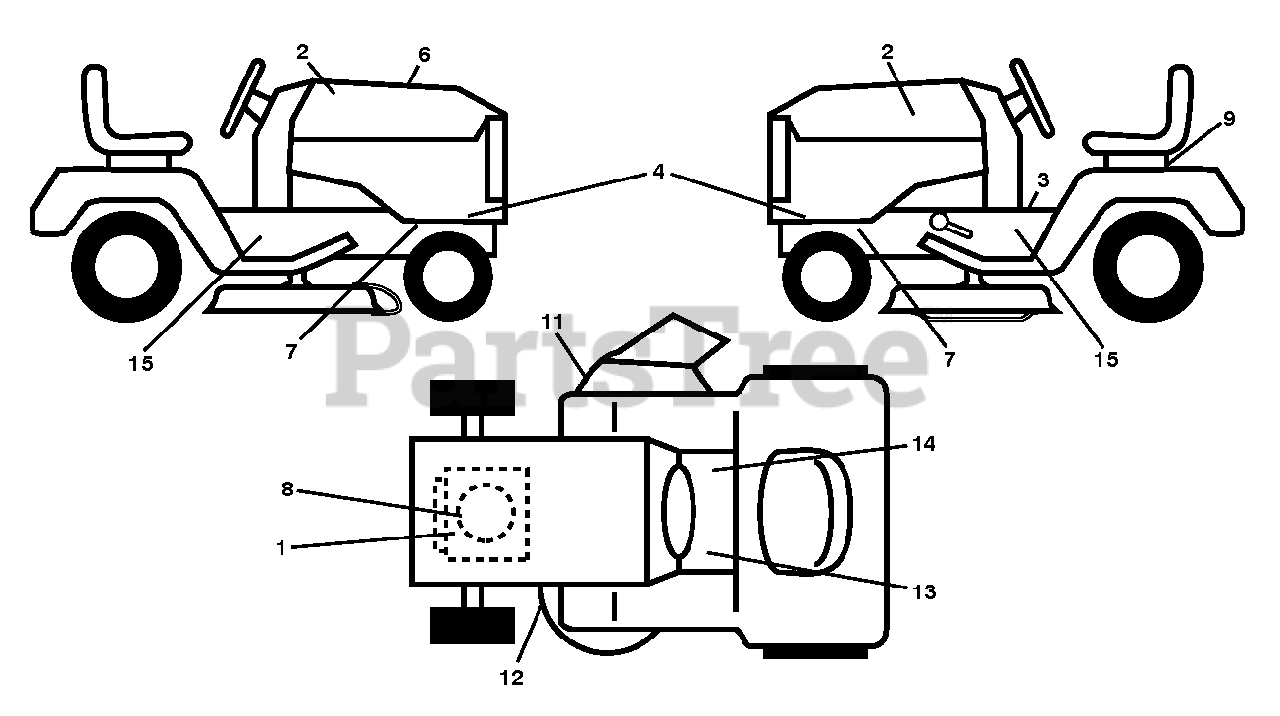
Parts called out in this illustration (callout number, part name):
1	DECAL.ENGINE.WARNING
2	DECAL.BADGE.170MM.TEXTLOGO.
3	DECAL.READ.OWN.MAN.SYMBOL.LT
7	DECAL.CHASSIS.HOT.MUFFLER
8	DECAL
9	DECAL BTRY SYMBOLS
11	DECAL.WARN.DFLCTR/CTFNGR.SRD.
12	DECAL.V.BELT.30"
13	DECAL.FNDR.SDLE.BRAKE.CLUTCH.6
14	DECAL.PARKING.BRAKE.SADDLE.LT
15	DECAL.WARNING.SERVCE/FIRE
